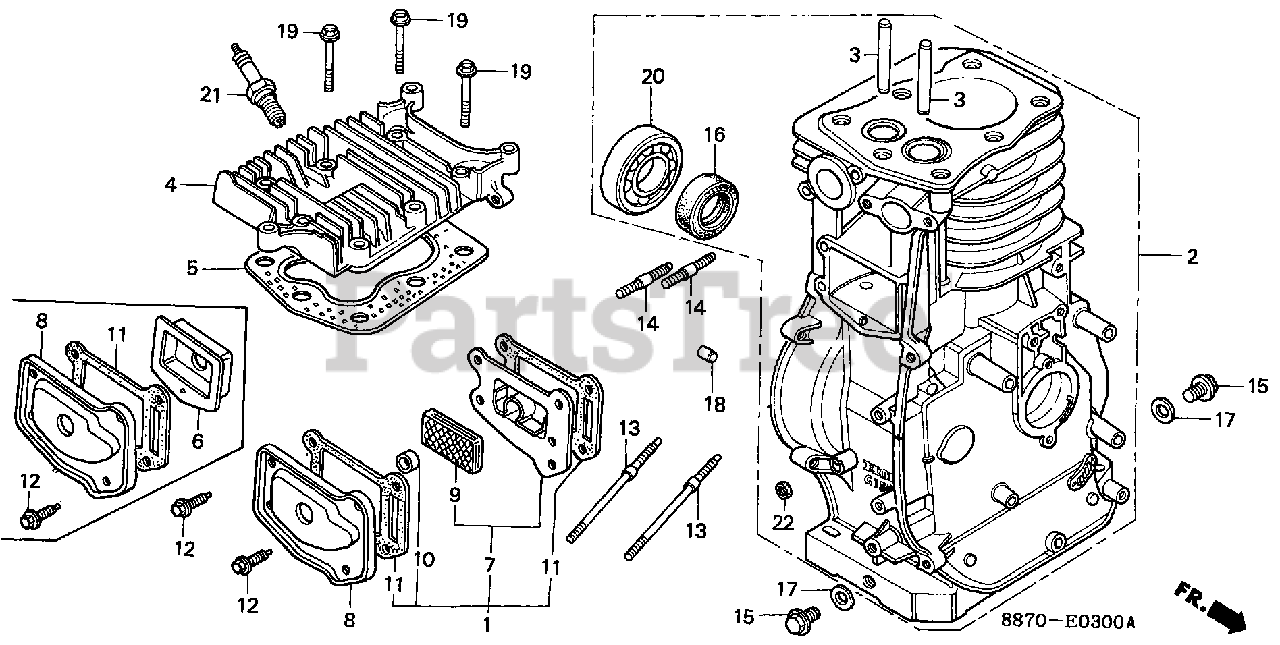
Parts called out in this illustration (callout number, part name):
1	CASE KIT, BREATHER Use up to Engine SN 1454980.
2	CYLINDER ASSY.
3	GUIDE, VALVE (OVER SIZE)
4	CYLINDER HEAD
5	GASKET, CYLINDER HEAD
6	CASE, BREATHER
7	CASE, BREATHER
8	COVER, TAPPET ROOM
9	FILTER, BREATHER
10	SEAL, BREATHER
11	GASKET, TAPPET COVER
12	BOLT, FLANGE (6X12) (CT200)
13	BOLT, STUD (6X95)
14	BOLT, STUD (8X35)
15	BOLT, DRAIN PLUG (12X15)
16	OIL SEAL (25X41X6)
17	WASHER, DRAIN PLUG (12MM)
18	PIN, DOWEL (8X14)
19	BOLT, FLANGE (8X45)
20	BEARING, RADIAL BALL (6205)
21	SPARK PLUG (B-4H) (NGK)
21	SPARK PLUG (W14F-U) (DENSO)
21	SPARK PLUG (W14FR-U)
21	SPARK PLUG (BP-4HS-10) (NGK)
21	SPARK PLUG (BPR-4HS-10) (NGK)
21	SPARK PLUG (BPR4HS-10)
21	SPARK PLUG (BP4HS-10)
21	SPARK PLUG (W14FP-UL10)
21	SPARK PLUG (W14FPR-UL10)
21	SPARK PLUG (B6HS) (NGK)
21	SPARK PLUG (BR6HS) (NGK)
21	SPARK PLUG (W20FS-U) (DENSO)
21	SPARK PLUG (W20FPR-U10)
